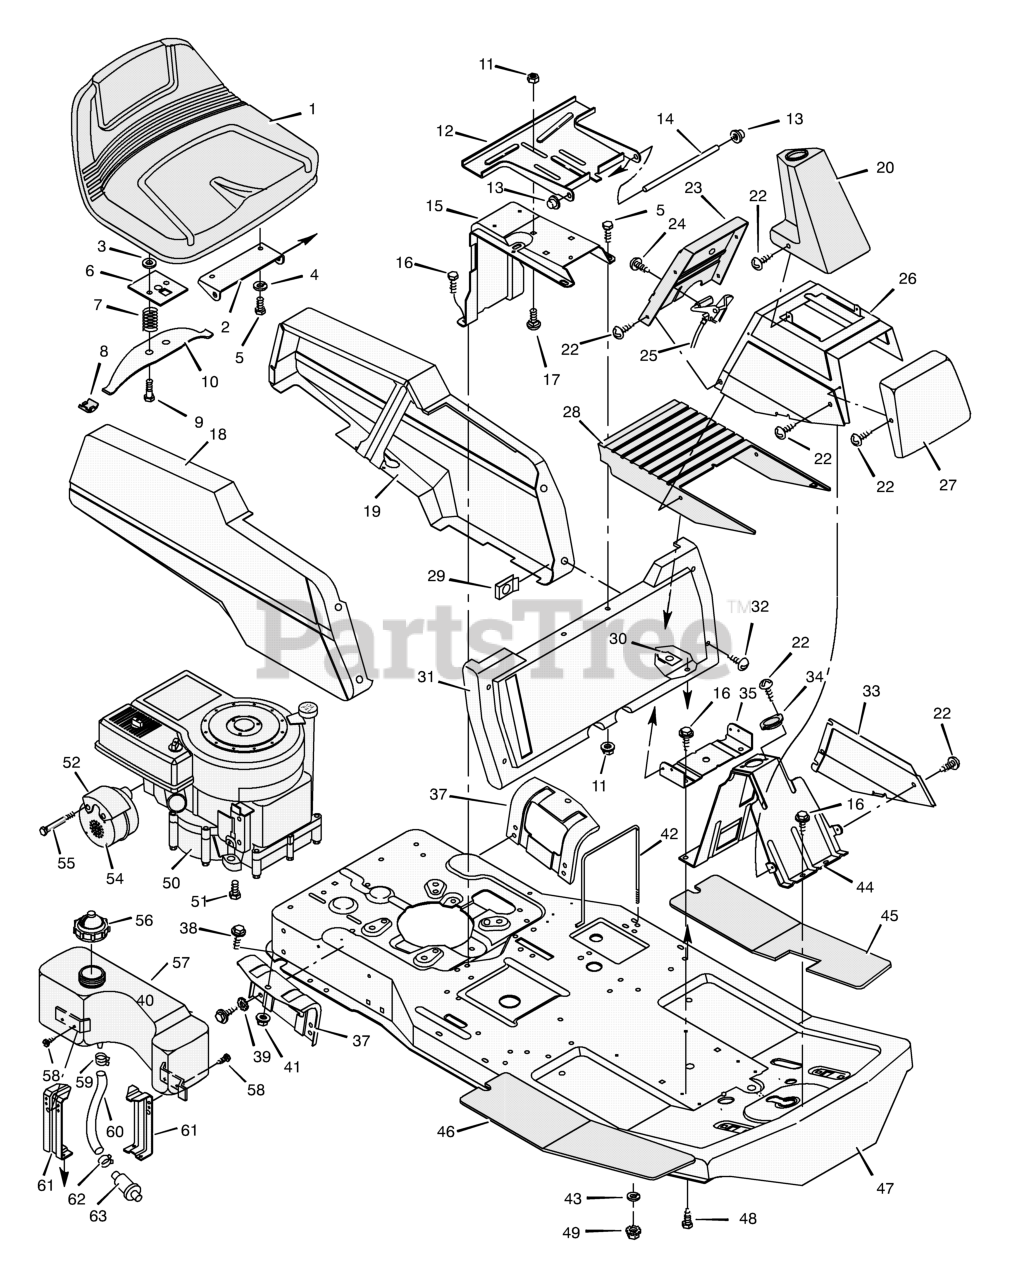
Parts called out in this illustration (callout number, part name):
2	Hinge, Seat
3	Retainer
4	Lockwasher
5	Bolt, Hex
6	Plate, Seat Switch
7	Spring, Compression
8	Glide, Seat Spring
9	Bolt, Shoulder
10	Spring, Seat
11	Locknut, Flange
12	Bracket, Seat Pivot
13	Cap, Push On
14	Rod, Seat Hinge
15	Support, Seat
17	Bolt, Carriage
18	Panel, Right Side
19	Panel, Left Side
20	Cover, Steering Column
22	Screw, Tapping
23	Panel, Control
25	Throttle Control
27	Cap, Front Console
28	Cover, Lower Console
29	Retainer
31	Panel, Front
32	Screw, Southco
33	Panel, Left Access
34	Bearing, Steering Post
35	Bracket, Cover Mounting
37	Support, Body
38	Bolt, Shoulder
39	Lockwasher
41	Locknut, Flange
42	Clamp Assembly, Battery
44	Support, Steering Column
45	Mat, Left
46	Mat, Right
49	Locknut
50	Engine, Briggs & Stratton *
51	Bolt, Engine Mount
52	Shield, Heat
54	Muffler
55	Bolt, Hex
56	Cap, Fuel
57	Tank, Fuel
58	Screw, Hex
59	Clamp, Hose
60	Line, Fuel
61	Bracket, Remote Tank
62	Clamp, Gas Line
63	Filter, Fuel
